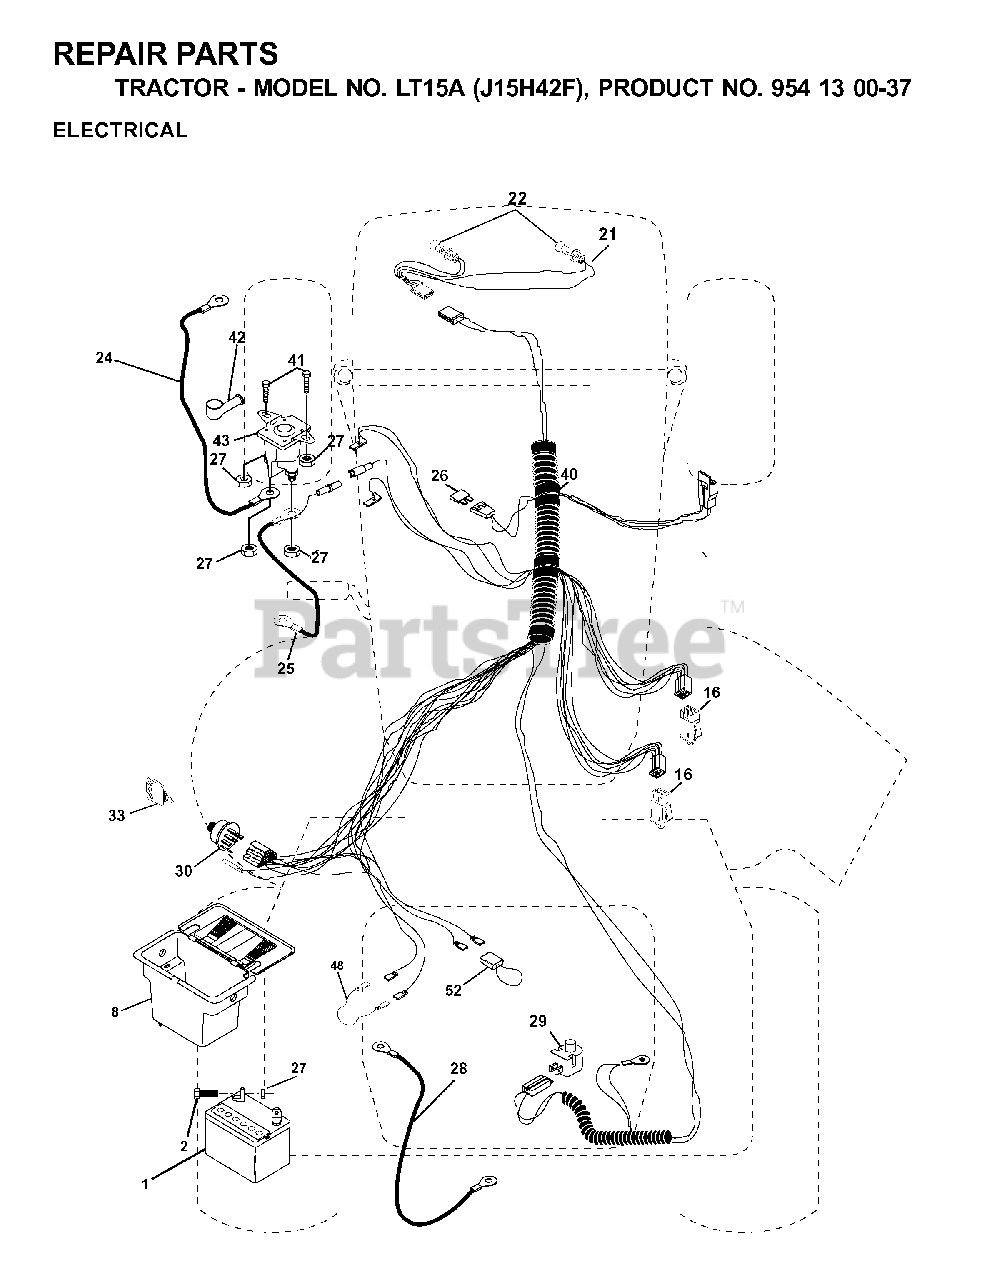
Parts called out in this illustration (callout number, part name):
1	BATTERY 12 VOLT 25 AMP
8	CASE BATTERY MECH HINGE
16	SWITCH INTERLOCK
20	NUT
21	HARNESS ASM, LIGHT W/4152J
22	LIGHTBULB
24	BATTERY CABLE GT
25	CABLE BATTERY
26	FUSE 15 AMP
27	NUT
28	CABLE T
29	SWITCH SEAT
33	KEY MLD GEN DELTA
40	HARNESS, IGN. LTH120
42	TERMINAL COVER
43	SOLINOID
52	WIRE PROTECTION LOOP
